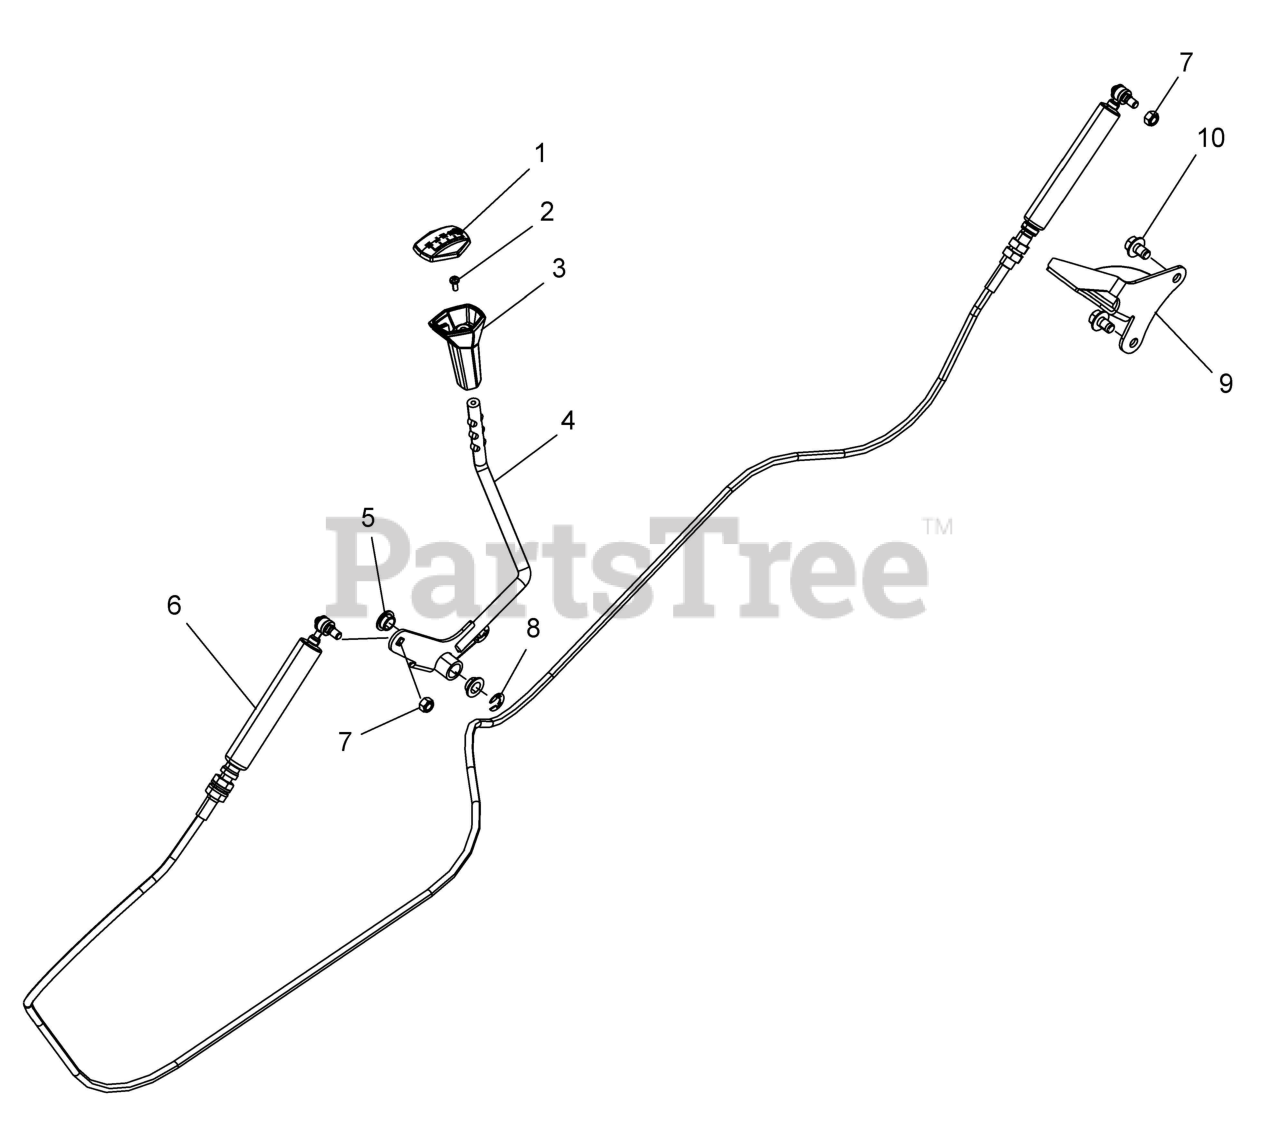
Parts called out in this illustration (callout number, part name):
1	COVER-SHIFT
3	KNOB-GEAR SELECTOR SHIFT
4	WELD-SHIFT LEVER,BLK
5	BUSHING-PEDAL PIVOT
6	CABLE, SHIFT
7	NUT,NYLOK M8X1.25(10) *
9	BRKT-SHIFT CABLE
10	BOLT-M10X1.25X16,HXHD,FLG
